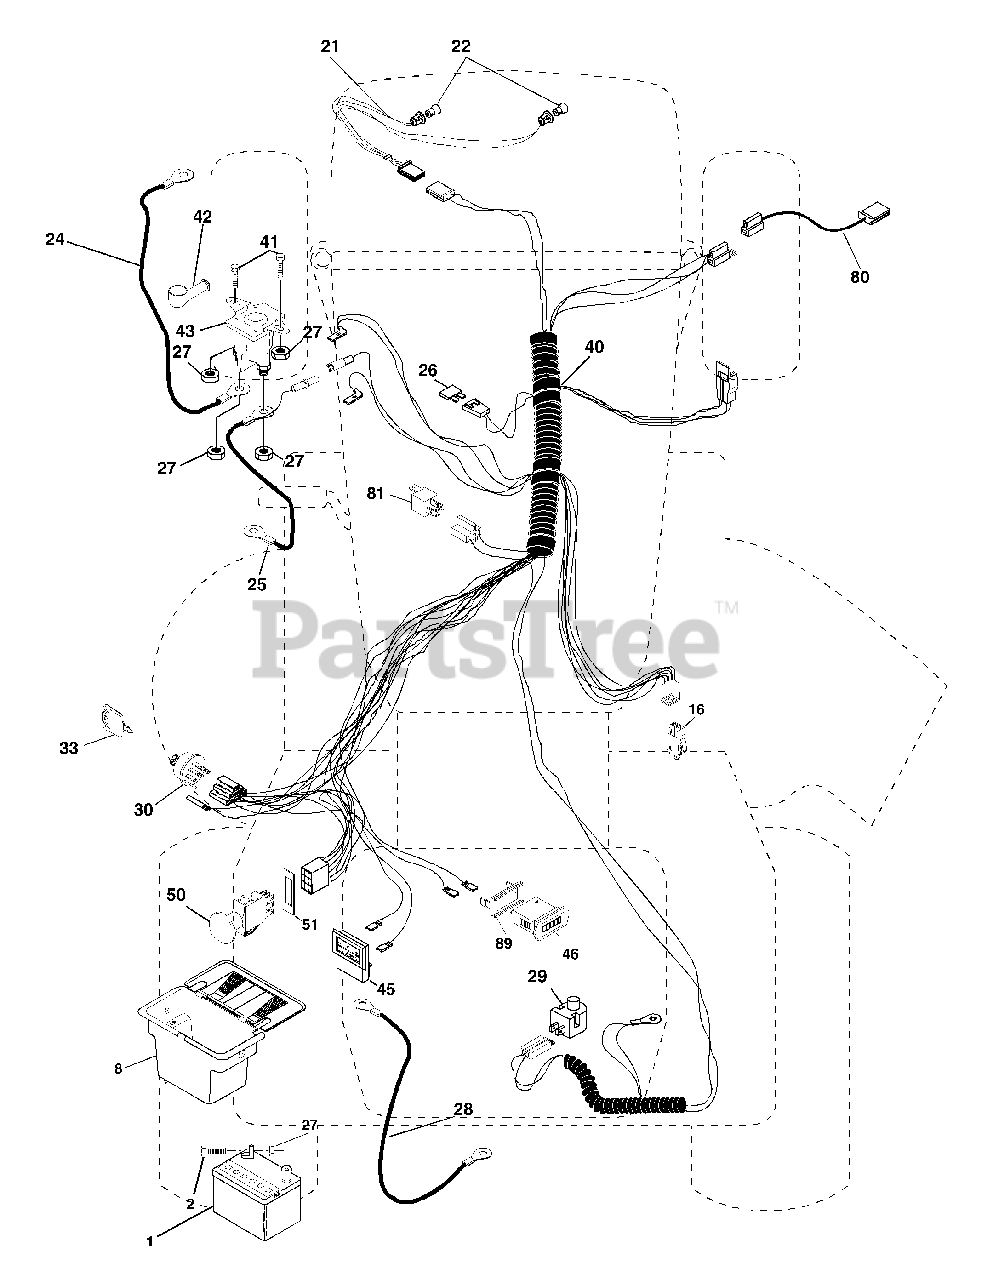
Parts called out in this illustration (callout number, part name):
1	Battery 12 Volt 25 AMP
2	Bolt Hex Hd 1/4-20unc X 3/4
8	Case Battery Mech Hinge
16	Switch Interlock Push-In
21	Harness Asm Light W/4152j
22	Bulb Light #1156
24	Cable Battery 6 Ga 11" red
25	Cable Battery 6 Ga 44" red w/16 wire
27	Nut Keps Hex 1/4-20 Unc
28	Cable Ground 6 Ga 12" black
29	Switch Plunger Nc Gray
30	Switch Ign
33	Key Ign Generic
40	Harness Ign.
41	Bolt Blk Fin Hex 1/4 - 20 x 1/2
42	Cover Terminal Red
43	Solenoid
45	Ammeter Rectangular 15 Amp
46	Meter Hour
50	Switch PTO
51	Ring Retainer PTO
80	Harness Clutch Evx
81	Relay Asm.
89	Bracket Snap-In Hourmeter
